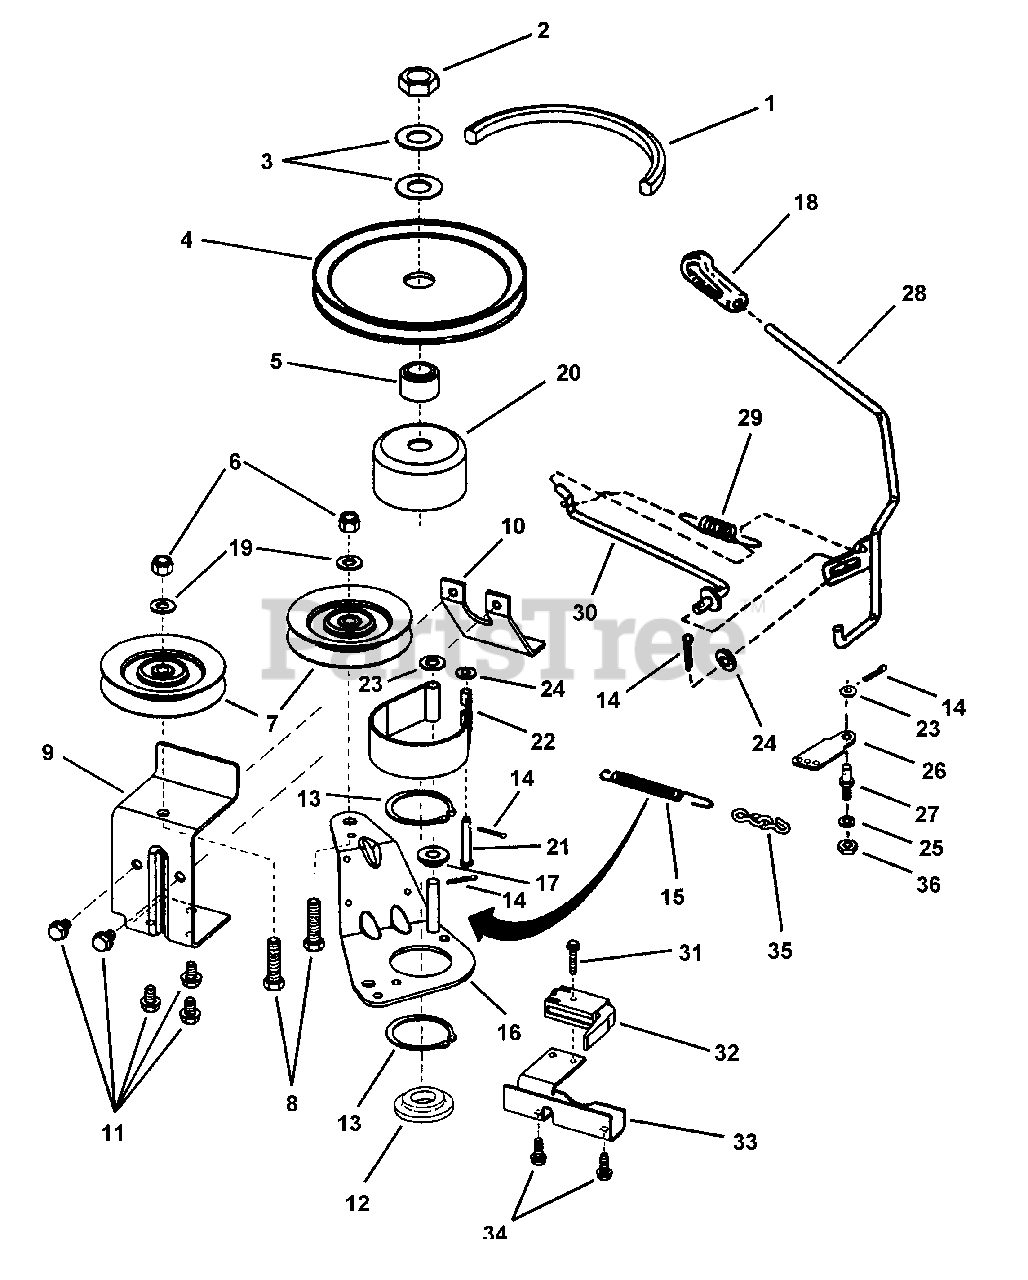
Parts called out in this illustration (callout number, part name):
1	BELT, Drive (73.75" AA Section)
2	NUT, 3/4-16 Hex Jam
3	WASHER, 49/64" I.D. x 1-1/2" O.D. Flat
4	PULLEY, Spindle
5	HUB, Pulley
6	NUT, 3/8-16 Nyloc
7	PULLEY, 4" Idler
8	SCREW, 3/8-16 x 1-1/2" Hex Head Cap, Grade 5
9	BRACKET, Fixed Idler
10	BRACE
11	SCREW, 5/16-18 x 1/2" Hex Washer Self-Tap
12	WASHER, Spindle
13	RING, 2" External Retaining
14	PIN, 3/32 x 3/4" Cotter
15	SPRING
16	ARM, Idler
17	SPACER
18	GRIP, Handle
19	WASHER, 3/8" Flat
20	DRUM, Brake
21	PIN, 1/4" x 1-5/8" Clevis
22	BAND, Brake
23	WASHER, 3/8" Flat
24	WASHER, 1/4" Flat
25	WASHER, 3/8" Split Lock
26	BRACKET, Brake Anchor
27	STUD (3/8-24 Thread)
28	HANDLE, Blade Lever (ON-OFF)
29	SPRING, Blade Handle
30	ROD, Idler
31	SCREW, #10-32 x 1" Hex Washer Self-Tap
32	SWITCH, Deck Interlock
33	MOUNT, Handle
34	SCREW, 1/4-20 x 5/8" Hex Washer Self-Tap
35	LINK, Chain
36	NUT, 3/8-24 Hex, Grade 2
